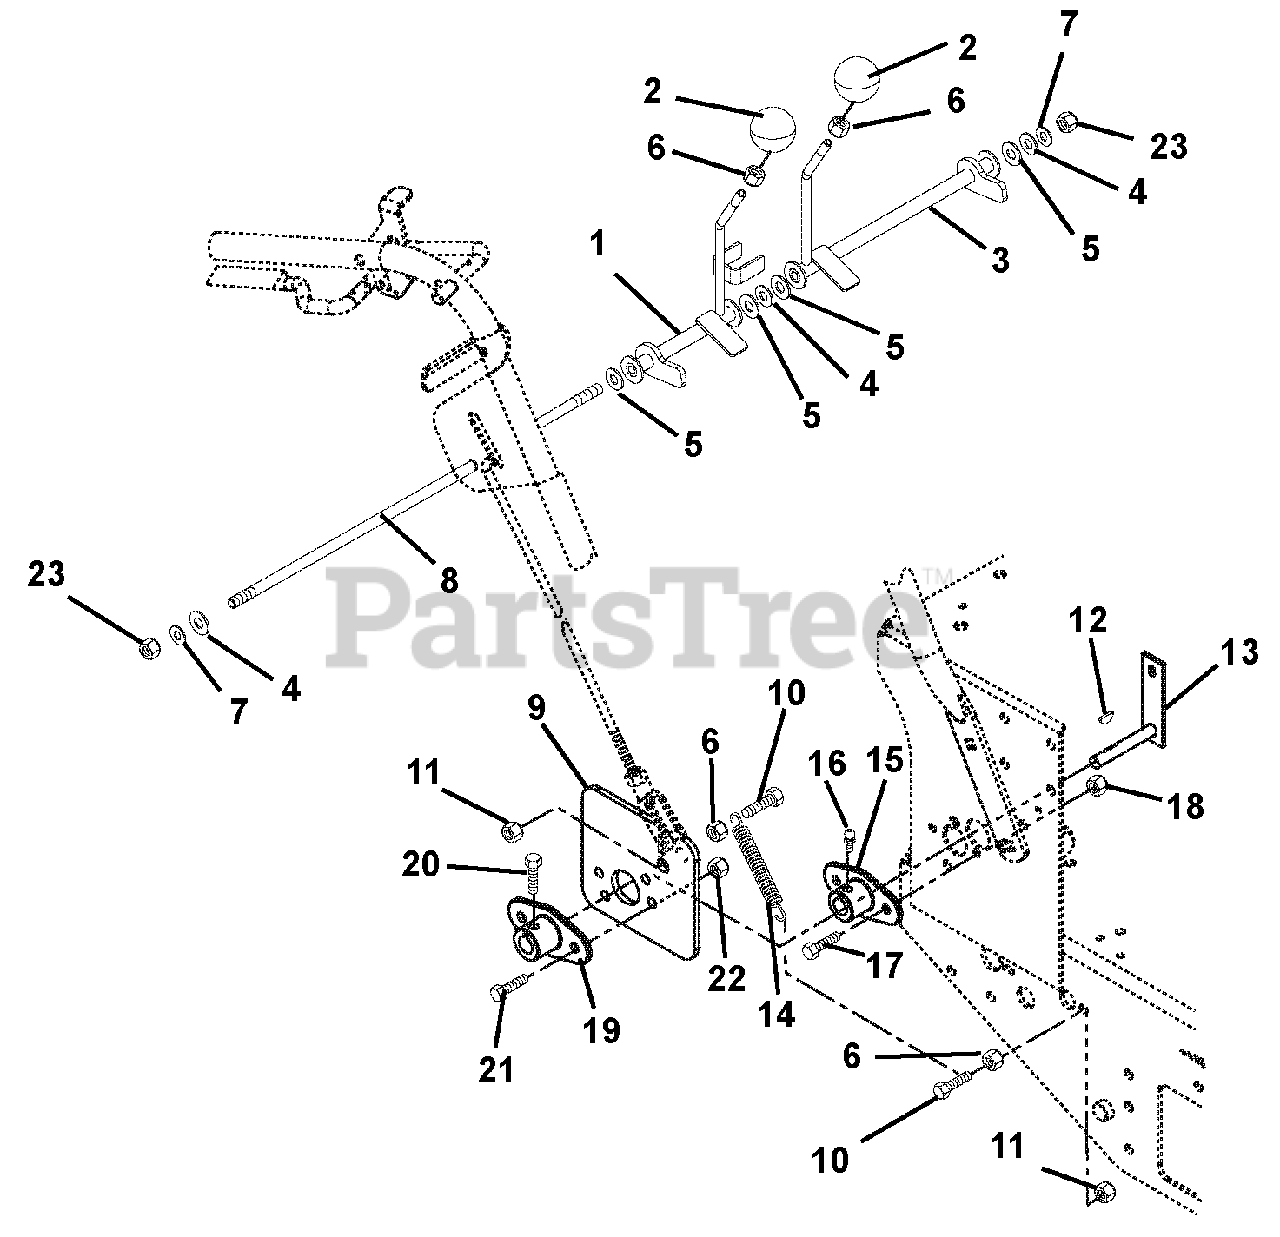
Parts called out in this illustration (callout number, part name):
1	Weldment, Right Hand Lever
2	Knob, Ball-Black 1-13/32, .375-16
3	Weldment, Left Hand Lever
4	Washer-Flat-Steel .406 x .812 x .065
5	Washer-Flat-Nylon .375 x 1.00 x .062
6	Nut-Hex .38-16
7	Washer-Locking .38 x .094 Regular
8	Rod, Speed Control
9	Plate, Speed Control
10	Bolt-Hex .38-16 x 1.50 Grade 5
11	Nut-Locking-Nylon .38-16
12	Key-Woodruff .125 x .75
13	Weldment, Pump Control Left Hand
14	Spring-Tension .105 x 1.00 x 5.0
15	Bushing, Flanged
16	Fitting-Lube .25-28 x .256
17	Bolt-Hex .31-18 x 1.00 Grade 5
18	Nut-Locking-Nylon .312-18
19	Arm, Speed Control
20	Bolt-Hex .25-20 x .50 Grade 5
21	Bolt-Hex .25-20 x .75 Grade 5
22	Nut-Locking-Nylon .25-20
23	Nut-Hex .375-24 Grade 2
